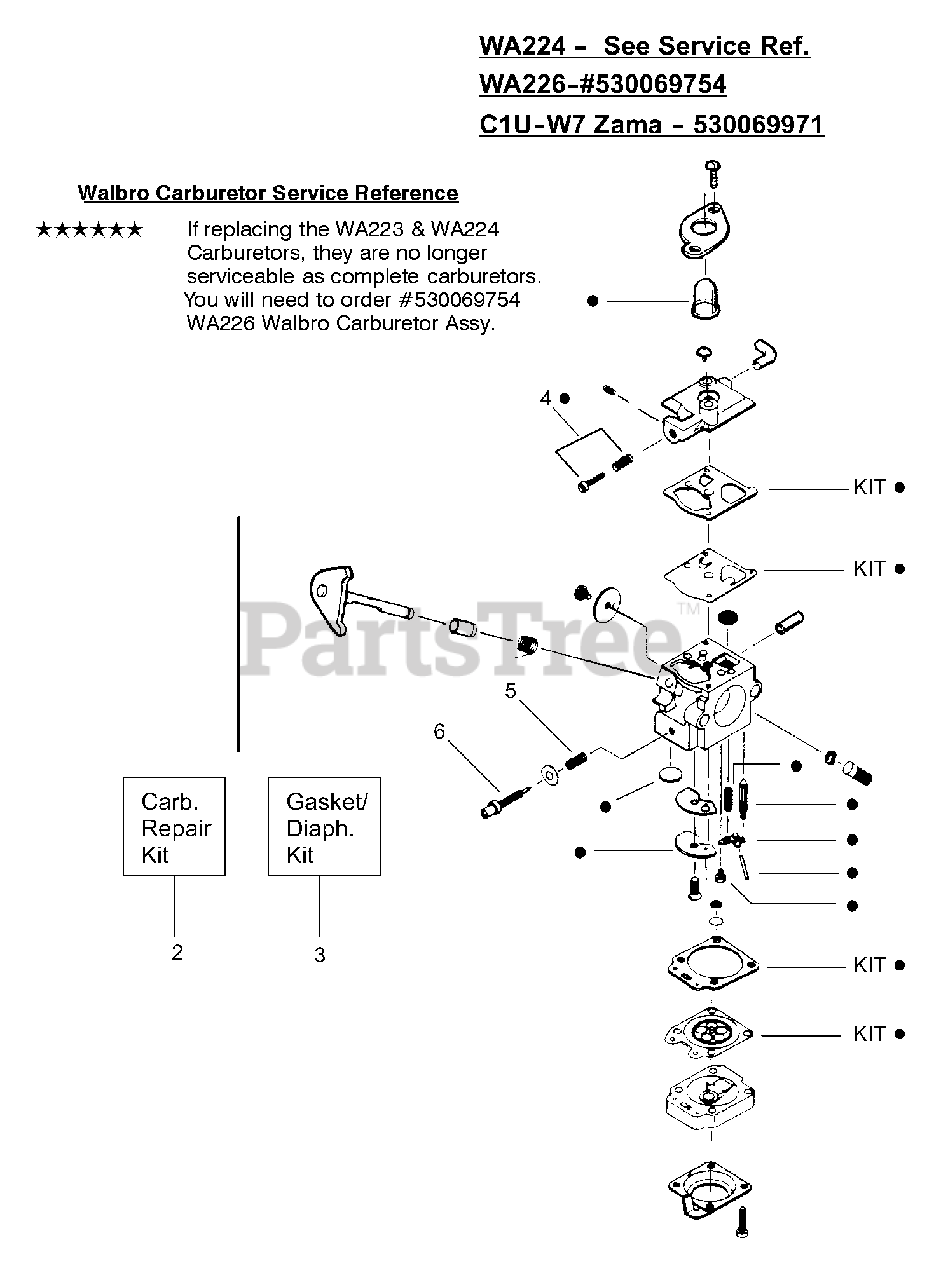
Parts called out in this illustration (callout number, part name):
2	Carburetor WA223
2	Carburetor WA224
2	Carburetor WA226
2	Carburetor C1U-W7
3	Gasket/Diaphragm WA223, WA224 & WA226
3	Gasket/Diaphragm C1U-W7 (Zama)
4	Idle Screw & Spring Kit
5	Low Speed Spring
6	Low Speed Needle
530069754	Carburetor Assembly (WA226)
530069971	Carburetor Assembly (Zama C1U-W7)
